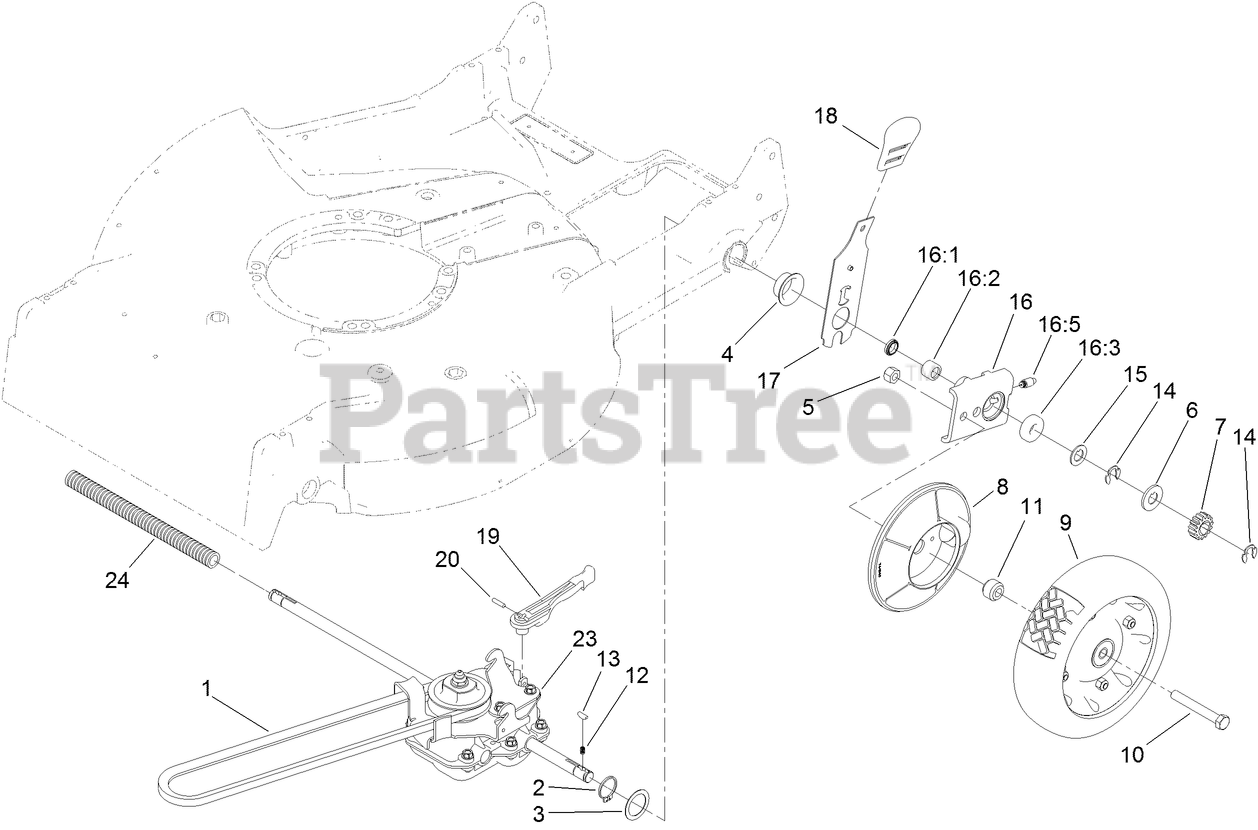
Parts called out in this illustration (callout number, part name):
1	V-BELT
2	RING-RETAINING
3	WASHER
4	CAP-END
5	NUT-LOCK, CONE
6	WASHER-THRUST, OUTER
7	GEAR-PINION
8	COVER-WHEEL
9	WHEEL AND TIRE ASM
10	SCREW-HH
11	SPACER-COVER, WHEEL
12	SPRING-COMPRESSION
14	RING-RETAINING
15	WASHER-THRUST, OUTER
16	PIVOT ARM ASM
16:1	SEAL-OIL
16:2	BEARING-CAGED NEEDLE ROLLER
16:3	BEARING-WHEEL
17	REAR SPRING ARM ASM
18	KNOB-HOC
19	LEVER-SHIFT
20	PIN-SPRING
23	GEAR CASE ASM
24	COVER-SHAFT, DRIVE
